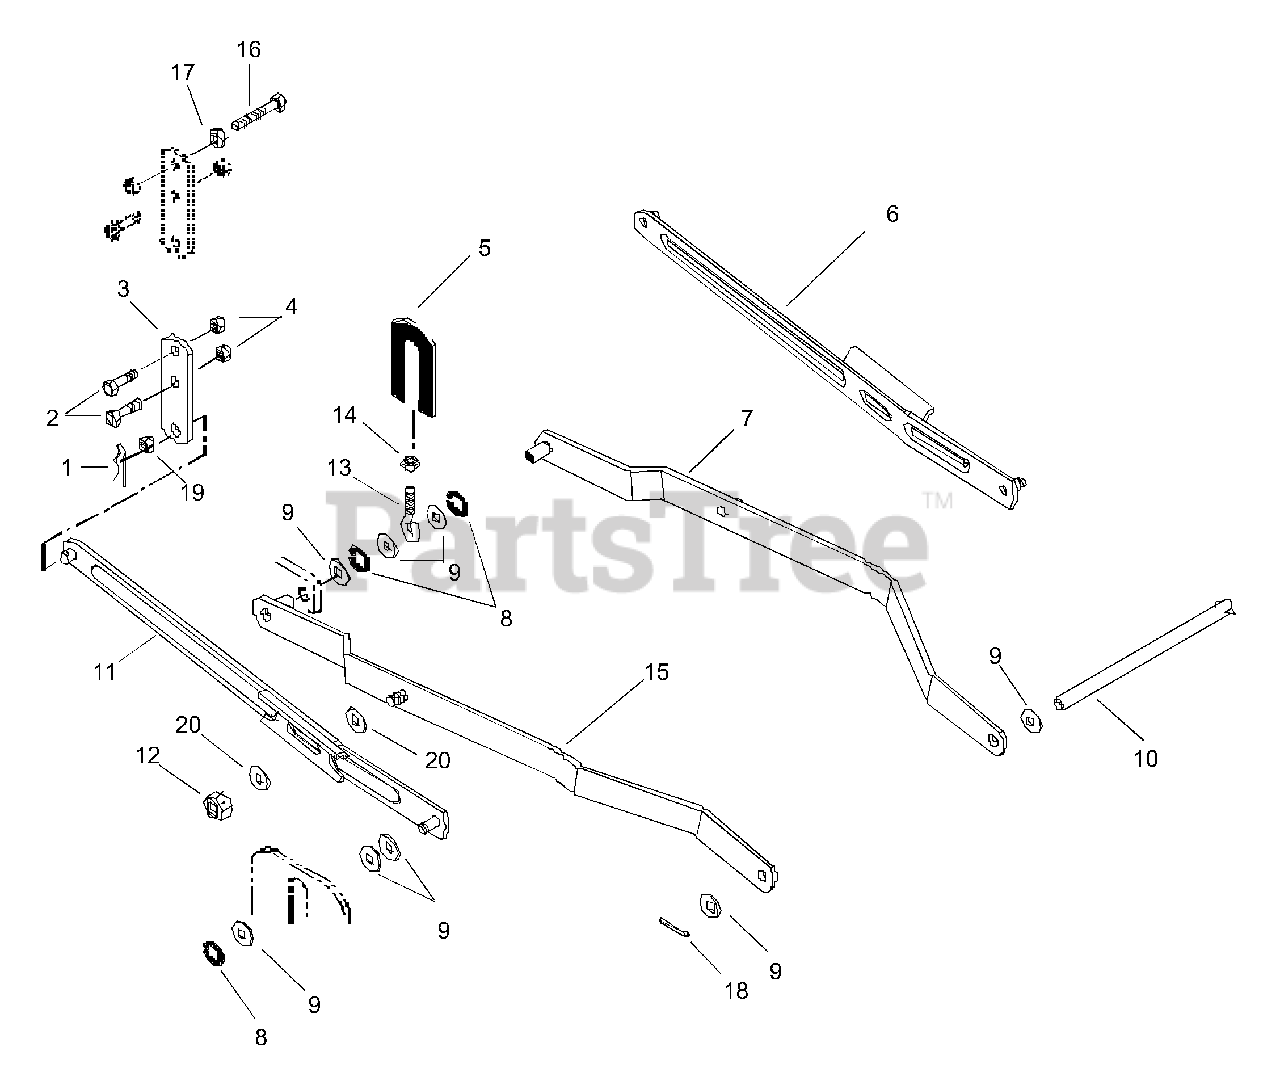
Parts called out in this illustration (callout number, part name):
1	Pin-Hair External .12 x .31 x 2.37
2	Bolt-Hex .38-16 x .75 Grade 5
3	Hanger Bracket
4	Nut-Locking-Center .375-16
5	Adjuster Link
6	Rear Hanger Left Hand
7	Left Hand Lift Arm
8	Ring-Retaining-External .500 x .050
9	Washer-Flat-Steel .531 x 1.062 x .095
11	Rear Hanger Right Hand
12	Nut-Locking-Center .62-11
14	Nut-Jam .375-16
15	Right Hand Lift Arm
16	Bolt-Hex .38-16 x 1.75 Grade 5
17	Nut-Hex .375-16
18	Pin-Cotter .12 x 1.0
19	Washer-Flat-Steel .630 x 1.005 x .062
20	Washer-Flat-Steel .656 x 1.31 x .095
